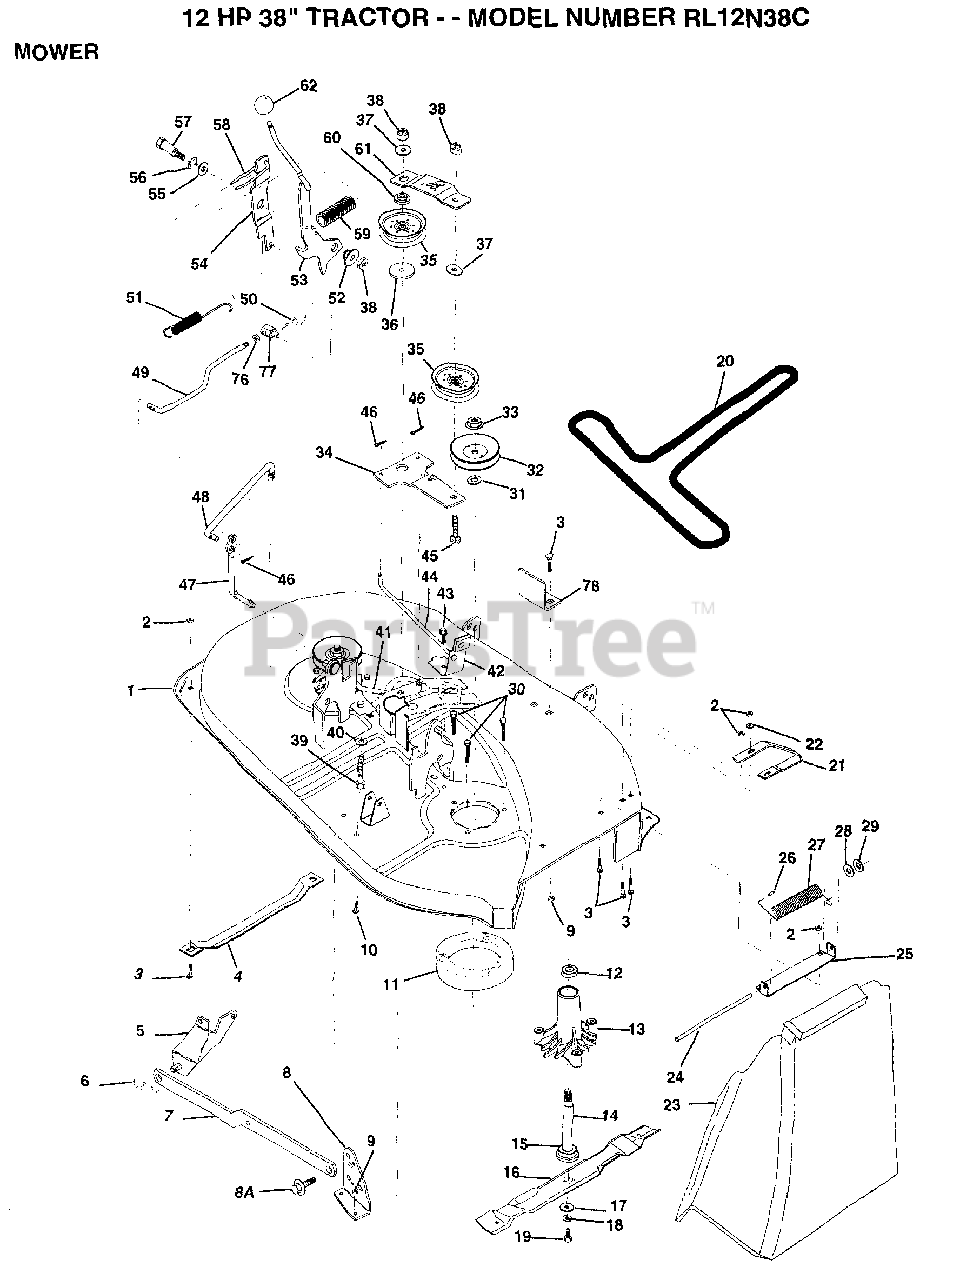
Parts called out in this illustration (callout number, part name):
2	NUT
3	BOLT
4	RUNNER-LH M
5	BRKT ASM SWAY BAR
8	BRKT DECK SW BAR
8A	BOLT SHD 5/16-18
9	NUT
10	BOLT
11	STRIPPER RND MWR
12	BEARING
13	HSG ASM MANDREL
15	BEARING.BALL
16	"BLADE.38""V.MULCH"
17	WASHER.HARD.BLADE
19	BLADE BOLT
20	V BELT
21	RUNNER RH
22	WASHER M
23	DEFLECTOR-SHLD T
24	ROD-HINGE T
25	BRKT DEFLECTOR
26	CAP-SLEEVE LT
27	SPRING TORSION
28	WASHER
29	NUT PUSH M
31	WASHER
34	IDLER ARM ASSY
35	FLAT IDLER PULLEY
36	SPACER RETAINER
37	WASHER GT
38	NUT
39	BOLT
40	WASHER GT
41	BRAKE ROD LH
42	BRAKE ASM
43	SCREW
44	BRAKE ROD RH
45	BOLT
47	PIVOT ROD
48	CLUTCH ROD SECOND
49	ROD CLUTCH 38/42
50	RETAINER M
51	RETURN SPRING
52	BUSHING
54	CLUTCH ARM SECOND
55	WASHER
56	RING
57	SHOULDER BOLT
58	SPRING KEEPER
60	RETAINER SPACER
61	IDLER ARM STIFF
62	KNOB T(3/8 HOLE)
76	NUT
77	TRUNION ADJ
78	UPSTOP DECK FT 38
